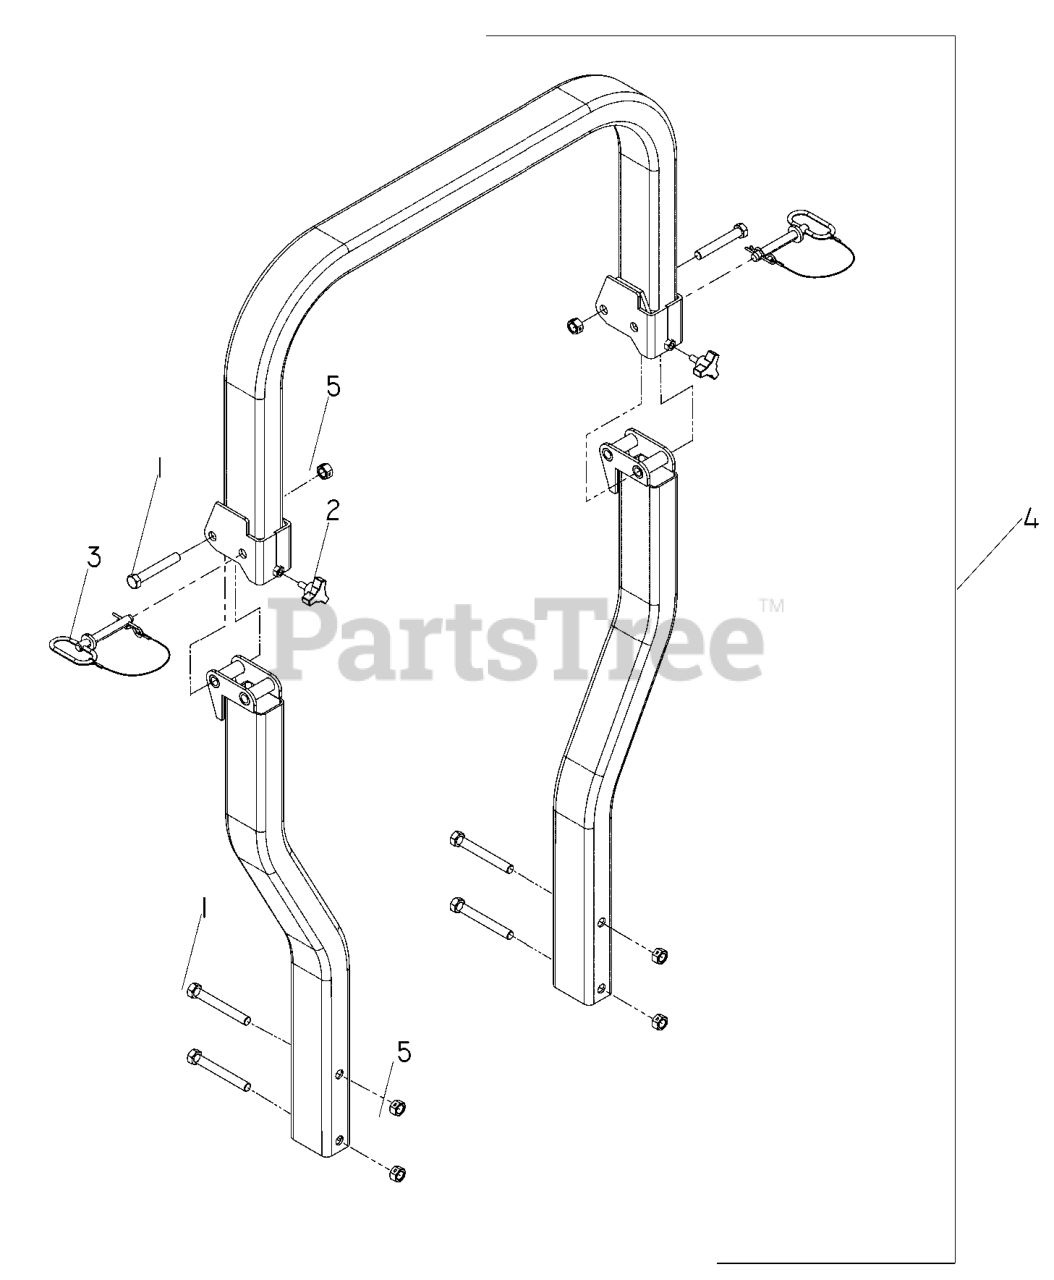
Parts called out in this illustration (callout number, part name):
1	HCS 1/2C X 3 1/4
2	KNOB W/STUD 3/8-16 X 1.5
3	PIN, 1/2" W/LANYARD
4	ROPS, COMP W/SEAT BELT
5	NUT 1/2-13 HEX CNTRLK GR 5 ZD
